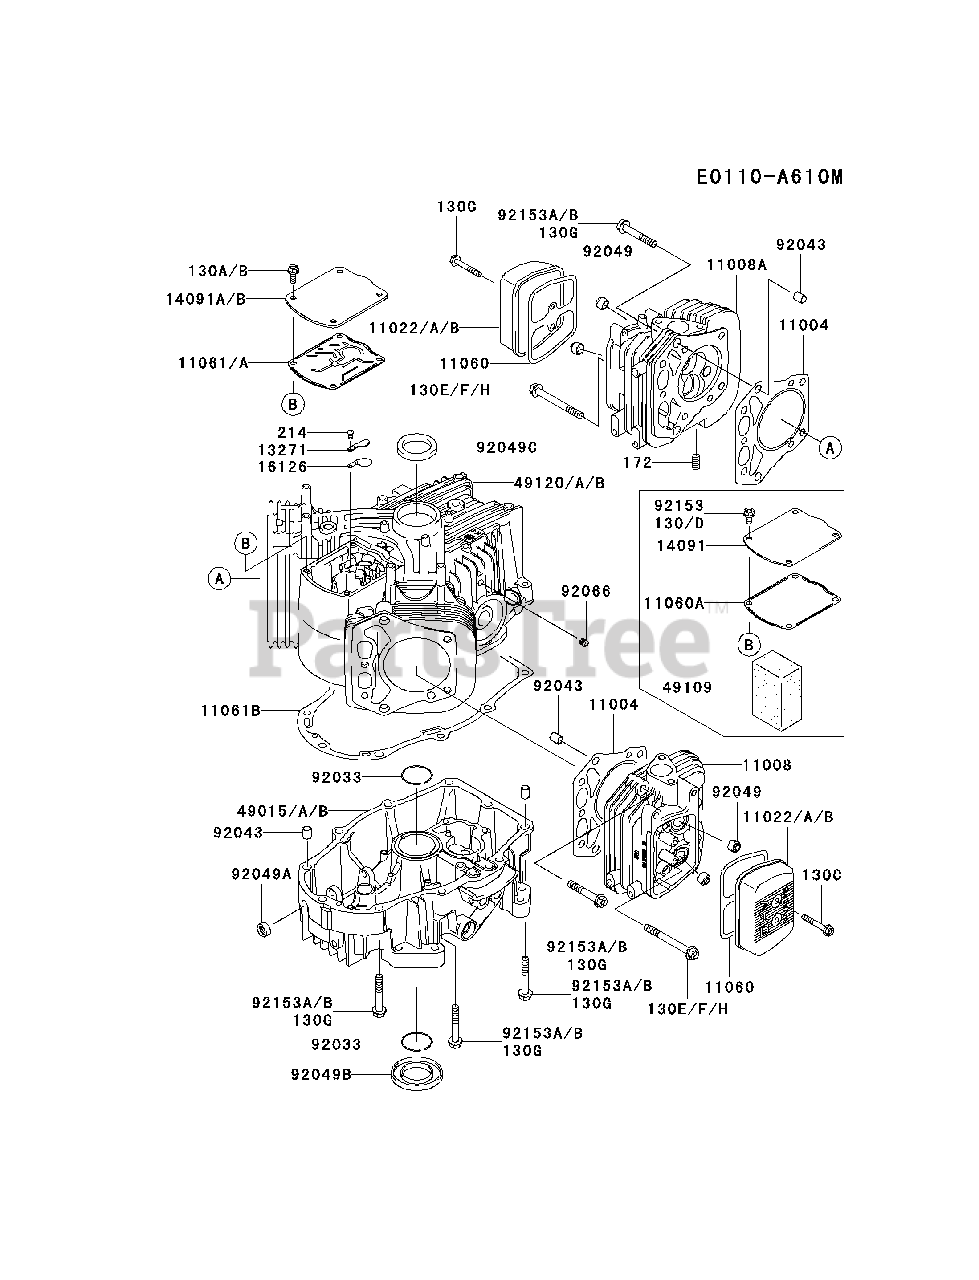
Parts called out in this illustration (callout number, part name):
130	BOLT-FLANGED,6X12
130B	BOLT-FLANGED,6X16
130C	BOLT-FLANGED,6X40
130D	BOLT-FLANGED,6X12
130F	BOLT-FLANGED,8X75
130G	BOLT-FLANGED,8X50
130H	BOLT-FLANGED,8X75
172	BOLT-STUD,8X18
214	SCREW-PAN+-,4X8
